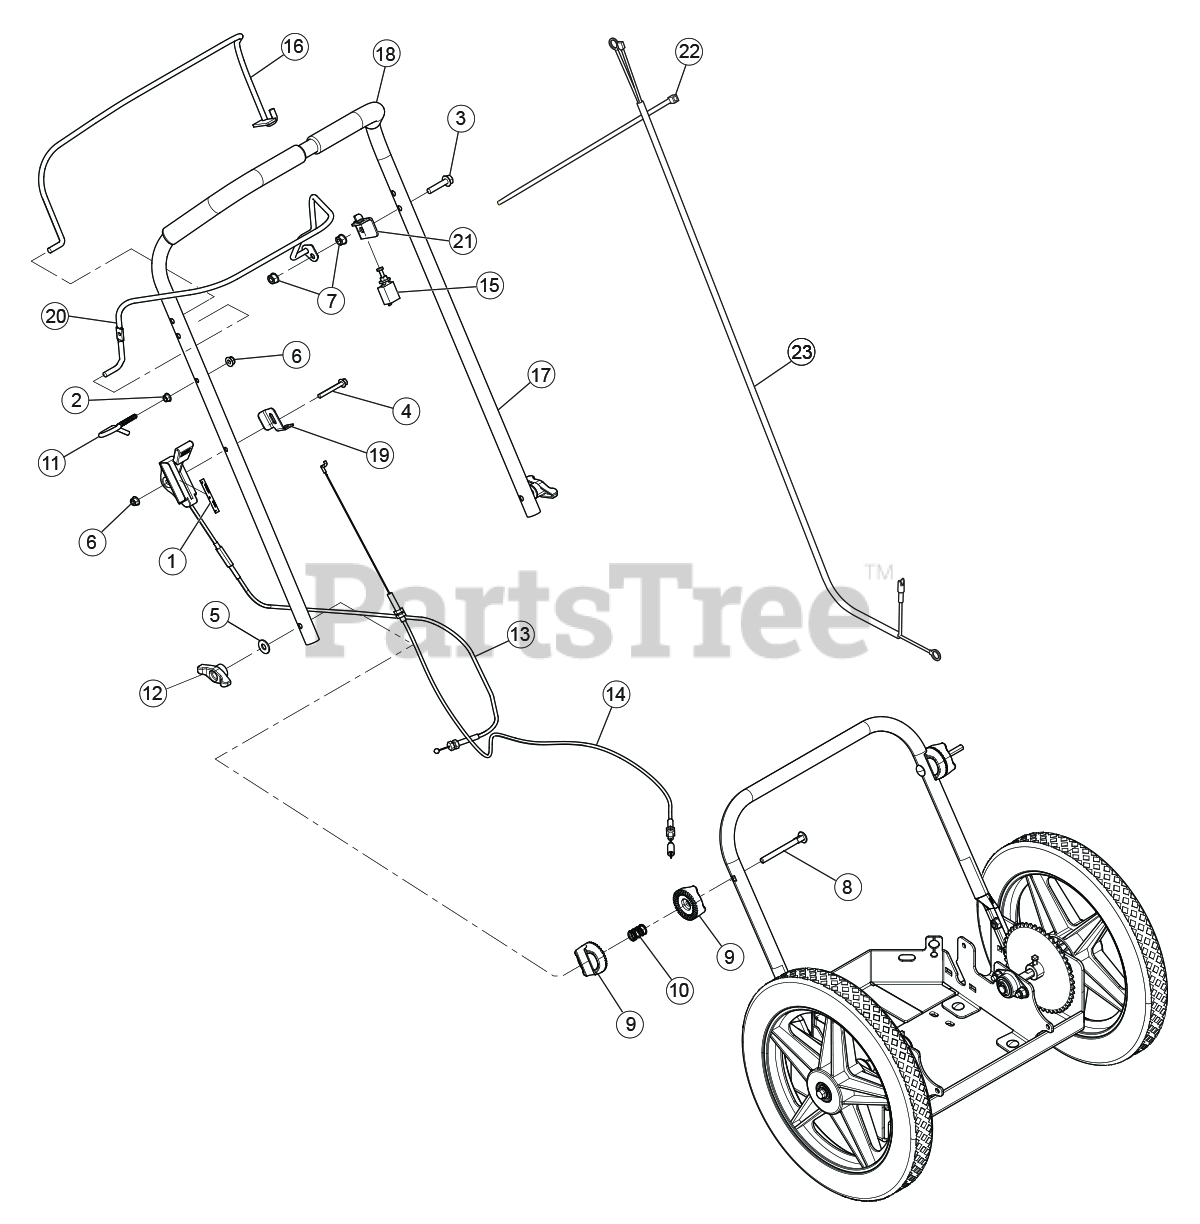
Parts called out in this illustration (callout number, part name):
1	DECAL, 3 SPEED
2	NUT, 1/4"-20 SERRATED FLANGE NC ZP
3	BOLT, 5/16 × 1-3/4 FLANGE NC
4	BOLT, 1/4 × 2 FLANGE NC
5	WASHER, 5/16 FLAT
6	NUT, 1/4-20 NYLOCK-FLANGE
7	NUT, 5/16-18 NYLOCK FLANGE
8	BOLT, 5/16-18 × 3-1/2 LONG NECK GR5 CRG ZP
9	RETAINER, HANDLE BAR ADJUSTMENT
10	SPRING, RETAINER COMPRESSION
11	GUIDE, RECOIL ROPE
12	KNOB, 5/16-18 FEEM TEE
13	CABLE, 3 SPEED WT
14	CABLE, TRANS ENGAGE WT
15	SWITCH, ENGINE KILL
16	ASSEMBLY, BAIL HW TRIMMERS
17	ASSEMBLY, UPPER HANDLE BAR WITH GRIPS
18	PAD, FOAM HANDLE BAR
19	BRACKET, WT ENGAGE CABLE
20	ASSEMBLY, BAIL WT TRIMMERS
21	BRACKET, HW KILL SWITCH
22	STRAP, 11 IN BLACK TIE
23	HARNESS, HONDA WT KILL SWITCH
